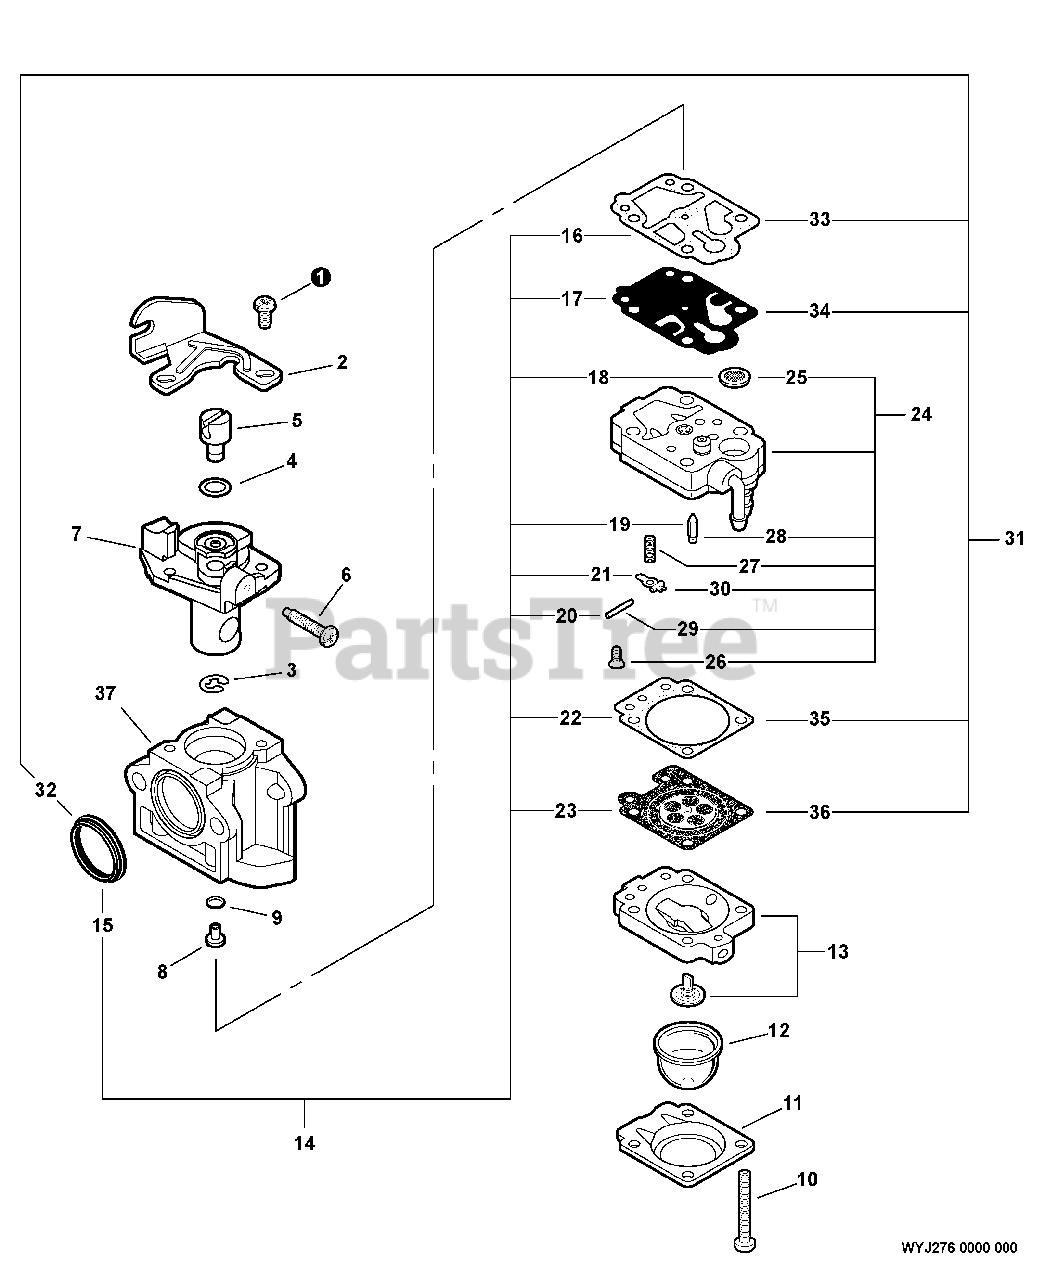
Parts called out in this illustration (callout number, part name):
2	BRACKET, CABLE
3	RING, RETAINING
6	SCREW, IDLE ADJUST
7	THROTTLE VALVE ASSY
10	SCREW, PUMP COVER
11	RETAINER, PURGE BULB
12	BULB, PURGE
13	PURGE BASE ASSY
14	REPAIR KIT
15	SEAL
16	GASKET, PUMP
17	DIAPHRAGM, PUMP
18	STRAINER
19	VALVE, INLET NEEDLE
20	PIN, METERING LEVER
21	LEVER, METERING
22	GASKET, METERING
23	DIAPHRAGM, METERING
24	BASE, PURGE
25	STRAINER
26	SCREW, METERING LEVER PIN
27	SPRING, METERING LEVER
28	VALVE, INLET NEEDLE
29	PIN, METERING LEVER
30	LEVER, METERING
31	DIAPHRAGM/GASKET KIT
32	SEAL
33	GASKET, PUMP
34	DIAPHRAGM, PUMP
35	GASKET, METERING
36	DIAPHRAGM, METERING
37	BODY, CARBURETOR
